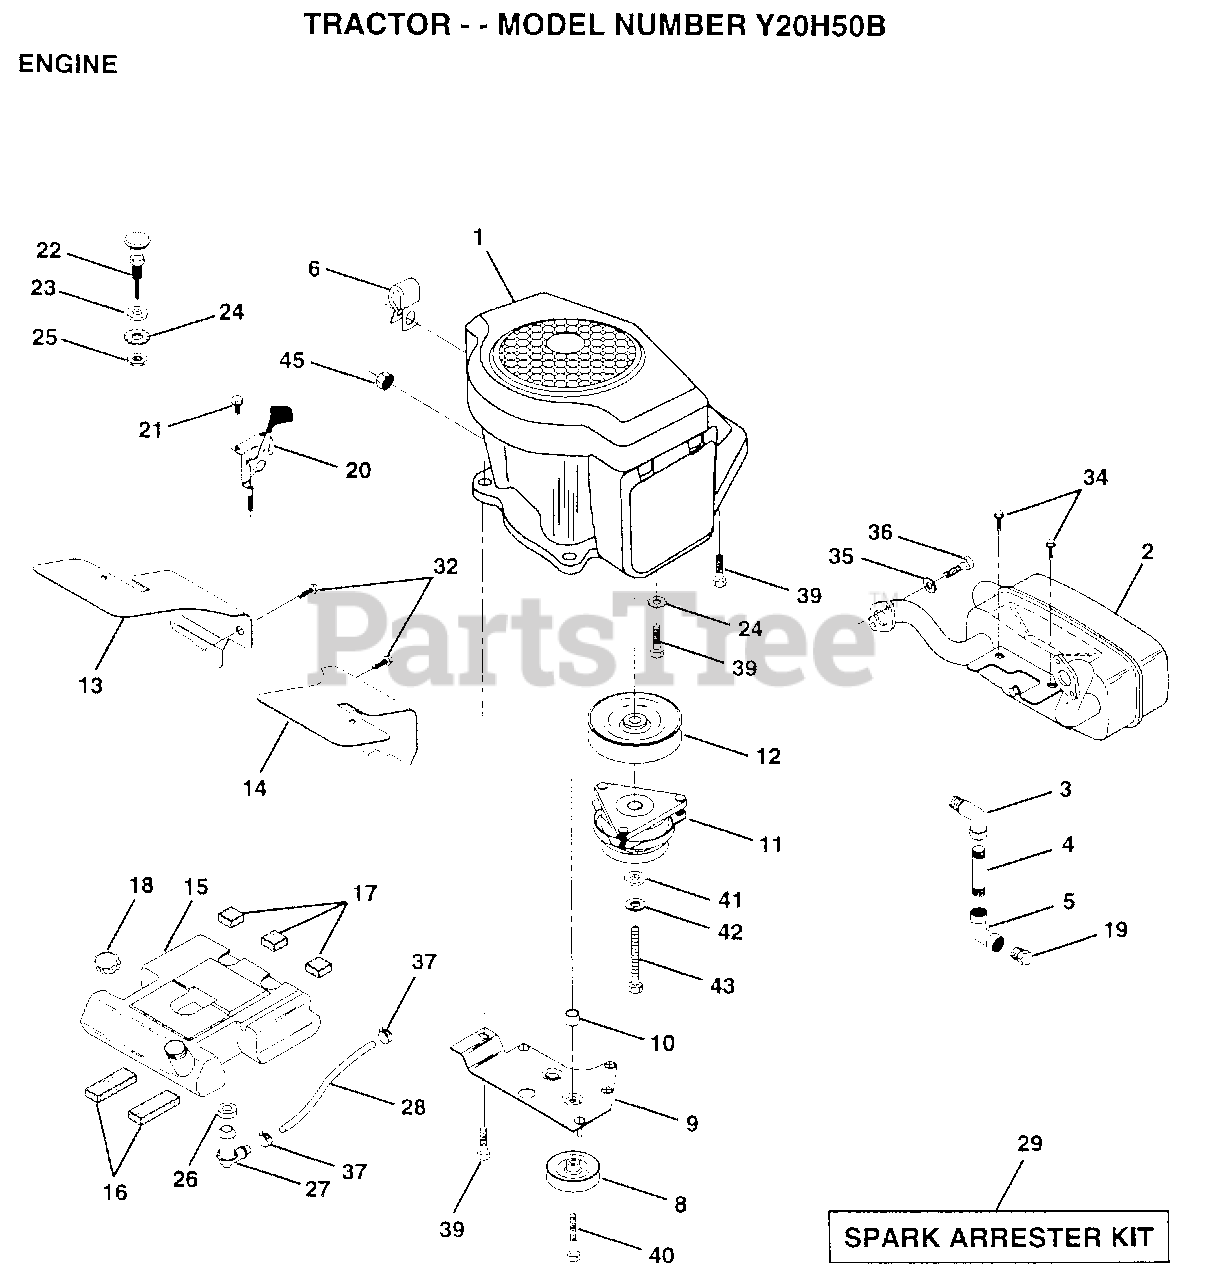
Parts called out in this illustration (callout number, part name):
2	MUFFLER.KOH.VCT.
3	STREET ELBOW LT
4	PIPE NIPPLE
5	ELBOW
6	CLAMP.TUBE.DBL.EN
10	BUSHING.
12	PULLEY.ENGINE.VGT
13	BAFFLE.AIR.LH.K
16	PAD IDLER TI
17	PAD-SPACER LT
18	CAP ASM FUEL
19	PLUG T
20	CONTROL THTL 37
21	SCREW LT
22	"CONTROL.CHOKE.51"""
23	WASHER
24	LOCKWASHER
26	BUSHING OUTLET T(1B5433551)
27	STEM.TANK.FUEL
28	Fuel Line
29	SPARK ARREST KIT
32	SCREW LT
34	SCREW
35	LOCKWASHER
36	SCREW
37	HOSE CLAMP
39	SCREW LT
40	SCREW.3/8-16X3.25
41	WASHER
42	LOCKWASHER
45	NUT
